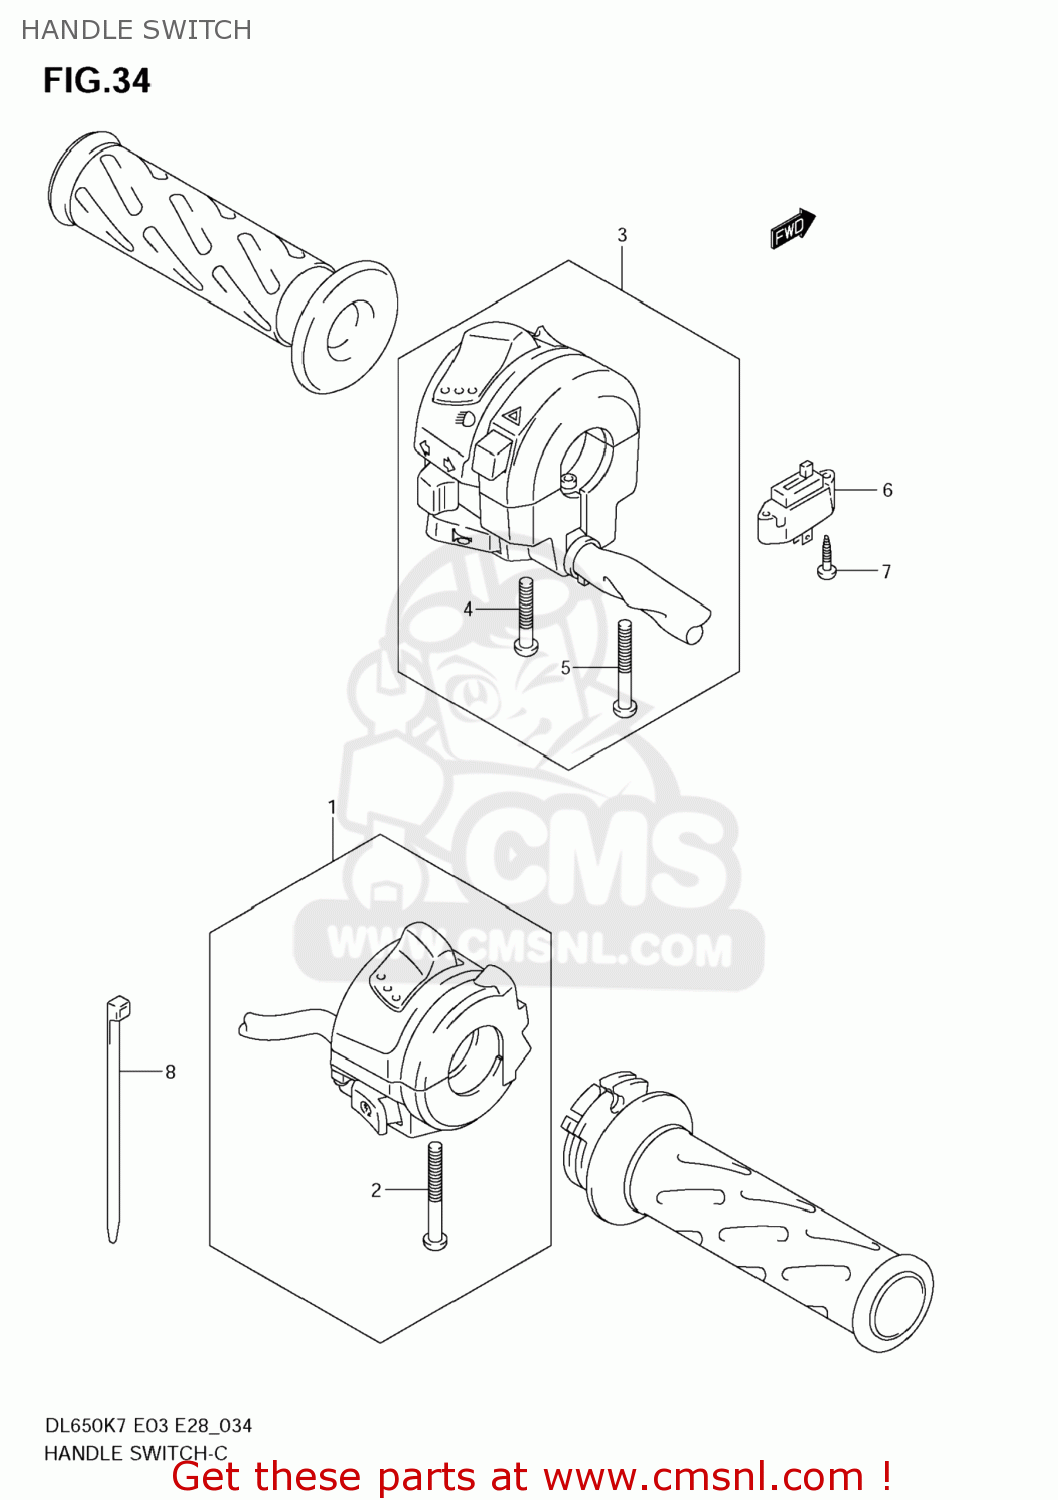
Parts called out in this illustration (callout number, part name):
1	SWITCH ASSY,HANDLE,R
2	SCREW
3	SWITCH ASSY,HA
4	SCREW
5	SCREW
6	SWITCH ASSY,CLUTCH
7	SCREW(3X14)
8	CLAMP(L:145)
